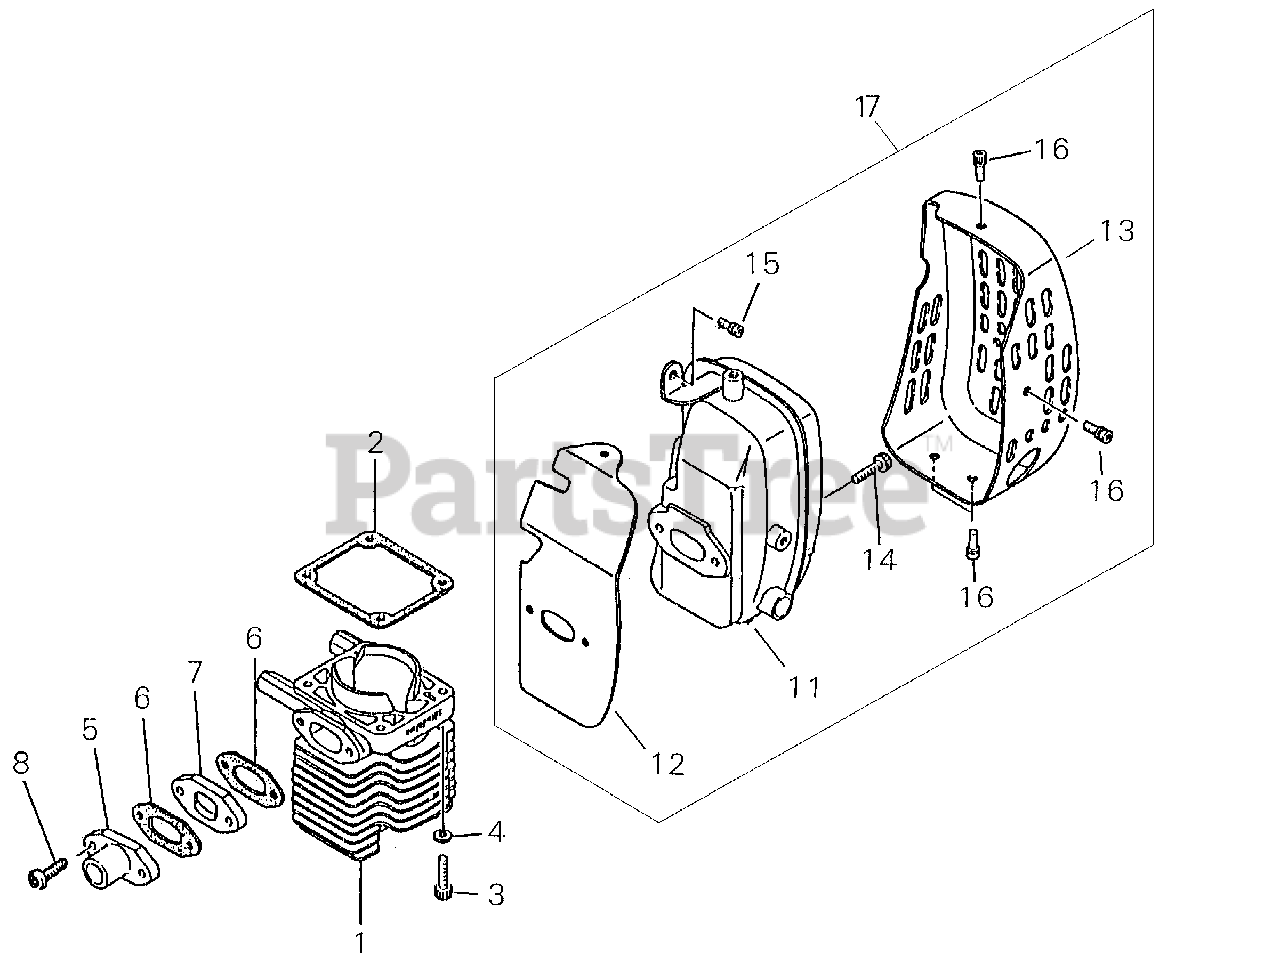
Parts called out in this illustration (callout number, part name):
1	CYLINDER
2	GASKET, CYLINDER
3	LOCKWASHER - 5
4	SCREW - 5X25
5	PIPE - INTAKE
6	GASKET, INTAKE
7	INSULATOR
8	SCREW - 5X20
11	MUFFLER
12	SHIELD, EXHAUST
13	COVER, EXHAUST
14	SCREW - 6X25
15	SCREW - 5X12
16	SCREW - 5X10
17	MUFFLER ASSY
